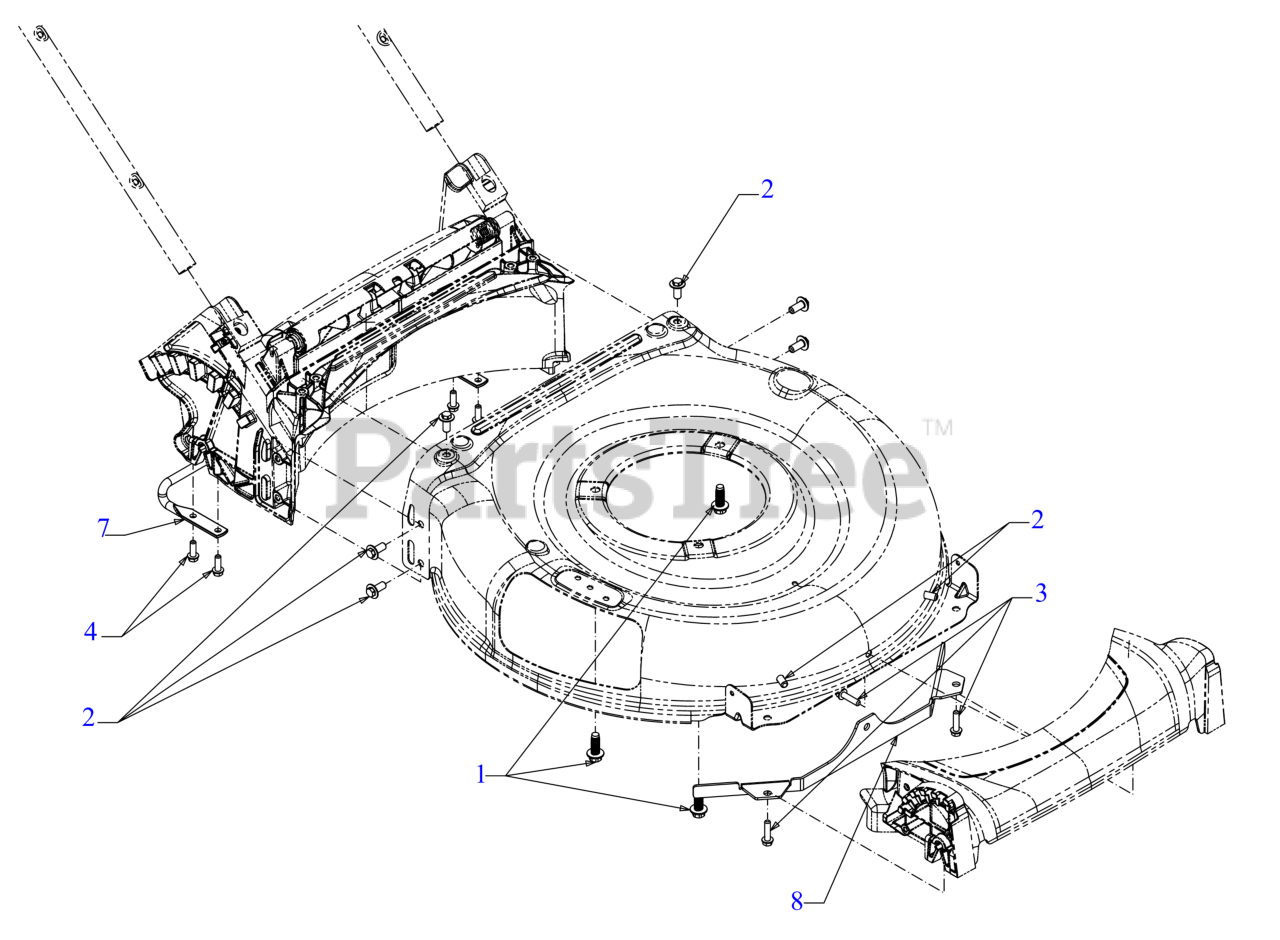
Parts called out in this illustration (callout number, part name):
1	SCREW 3/8-16 x 1
2	SCREW 5/16-14 x .750
3	SCREW 5/16-14 x 1
4	SCREW 1/4-15 x .750
7	TRAILSHIELD ROD
